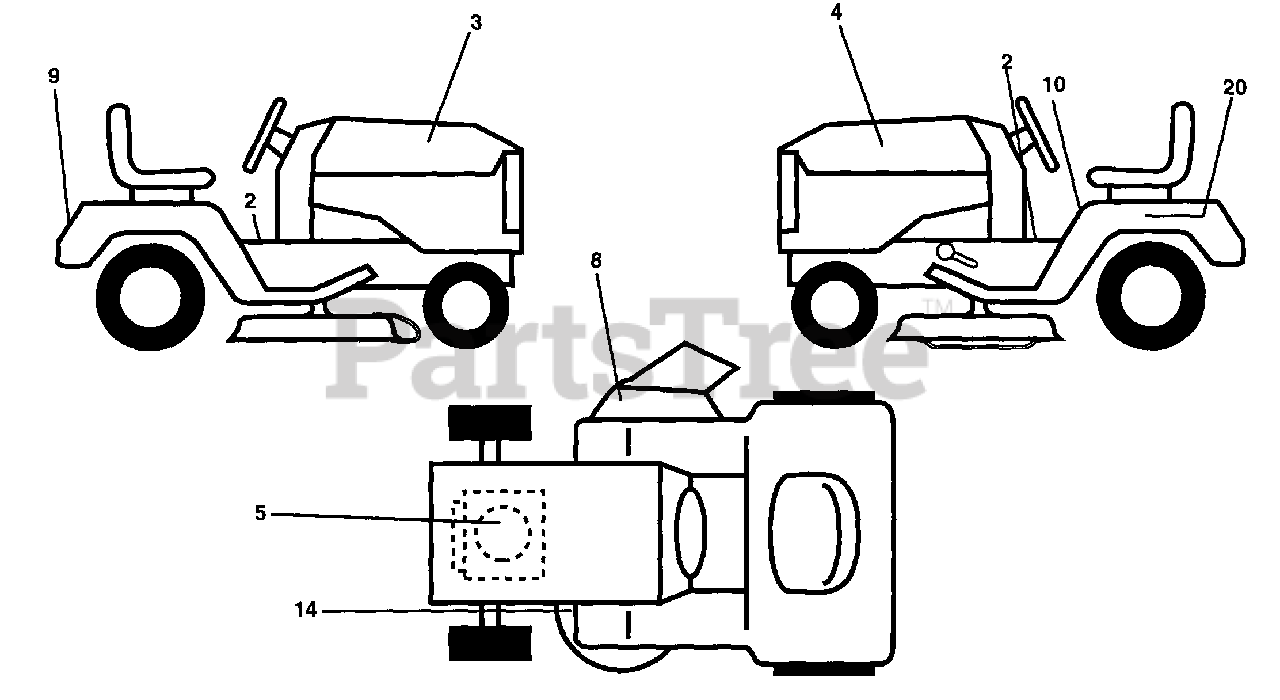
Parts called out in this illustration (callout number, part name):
2	Decal Fender STLT Oper. Inst. English/French
3	Decal Hood LH
4	Decal Hood RH
5	Decal HP Engine
8	Decal Warning Multi-Language
9	Decal Fender Husq
10	Decal Fender Danger Eng/Fr.
14	Decal V-Belt Schematic
20	Decal Bat Dan/Psn
